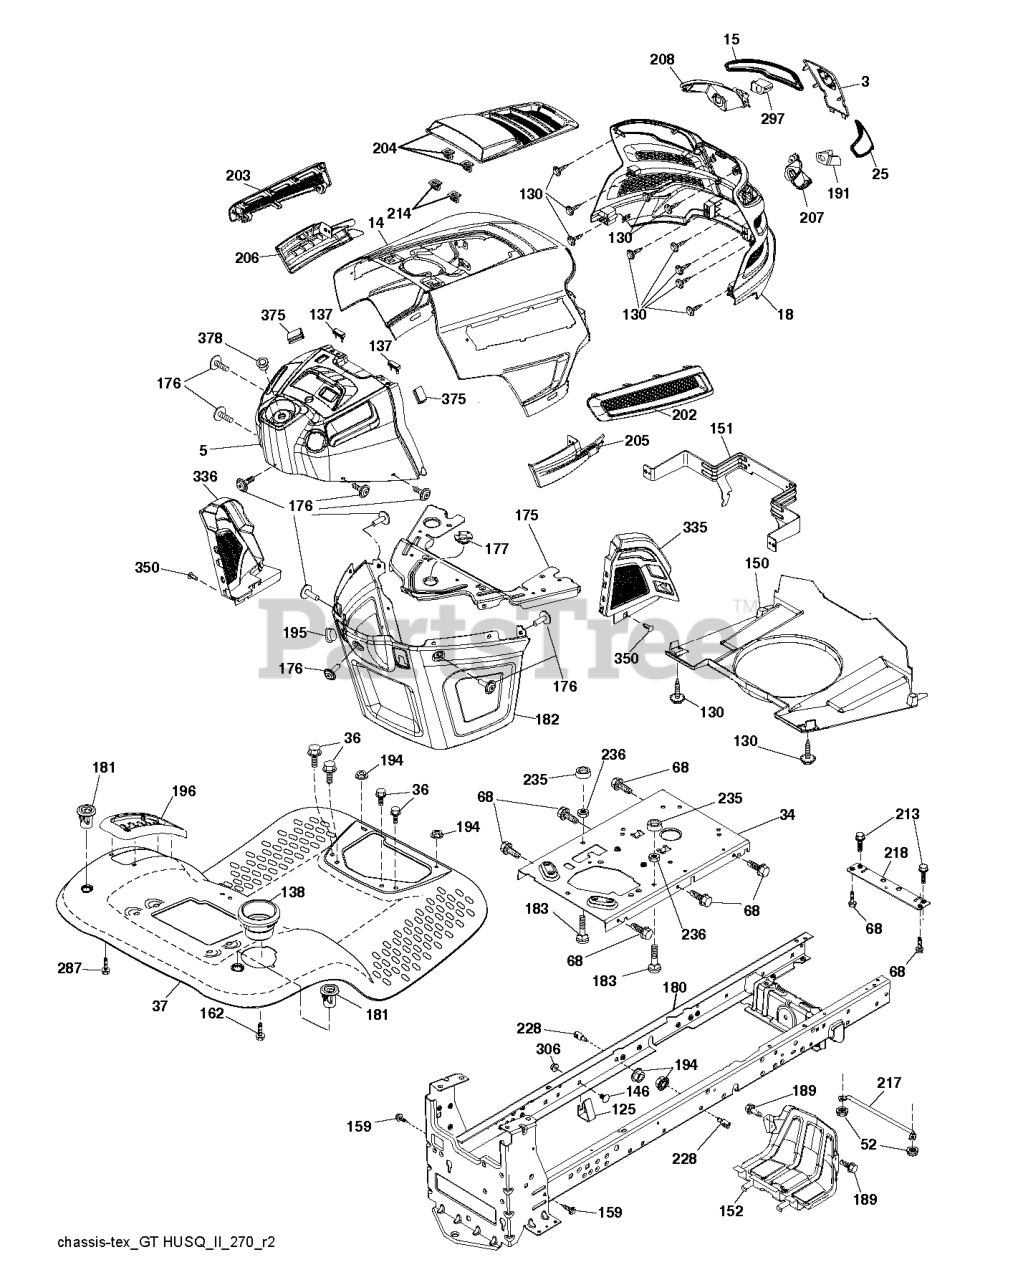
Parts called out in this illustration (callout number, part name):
3	APPLIQUE.SUBASM.GT.HUSQ.II
5	DASHBOARD.UPPER.ASM.GT2.X498
14	HOOD.ASM.HUSQVARNA.GT.TEX.ORAN
15	LENS.HEADLIGHT.LH.GTII.2011
25	LENS.HEADLIGHT.RH.GTII.2011
34	PLATE.ENGINE.WELDED.CHASSIS
36	SCREW 5/16"
37	FENDER.TLT.PDL.CNTRL.W/CPH.ORG
125	CLIP.FUEL.LINE
137	BUMPER DASH
138	HOLDER.CUP.LT.GREY
146	BOLT.RDHD.SHT.SQNK.3/8-16X5/8
150	AIR.DUCT.GTV2(2.54"RING HEIGHT
151	BRACKET.PIVOT.HOOD.GT.HUSQ.II
152	SHIELD.BROWNING.PNT.GT.V2
159	SCREW, 3/8-16X3/4
175	PLATE.PNT.CROSSMEMBER.HUSQ/PRE
176	SCREW.#10-24X5/8.RN.QU
177	BUSHING STEERING
180	CHASSIS
181	BUSHING.MNT.FEND.CRGO.TEX.49
182	DASH LOWER.HUSQ.PRED NO CRUISE
189	SCREW
191	INSERT.REFLECTIVE.RH.HUSQ.GTII
195	PLUG.HOLE.DASH.LOWER.12V.BLK
196	DECKLFT.CONSOL FULL ASSM GREY
202	VENT.SIDE.RH.GT.HUSQ.II.
203	VENT.SIDE.LH.GT.HUSQ.II.498
204	VENT.TOP.ASM.HUSQ.GT2
205	SIDE.TRIM.RH.GT.HUSQ.II
206	SIDE.TRIM.LH.GT.HUSQ.II.GRAY
207	HEADLIGHT.CUP.BEZEL.HUS.GT2.RH
208	HEADLIGHT.CUP.BEZEL.HUS.GT2.LH
213	SCREW HEXAGON HEAD SCREW 5/16-
214	CLIP.RETAINER.TINNER.
217	ROD.PIVOT.HOOD
218	X-PIECE.HOOD.STOP.NON/
228	STUD.W/"D"ANTI-ROTATION
236	NUT.CENTERLOCK.5/16-
287	SCREW 1/4X20
297	INSERT.REFLECTIVE.LH.HUSQ.GTII
306	NUT LOCK FLG 3/8-16 UNC
335	COVER.LOWER.DASH.RH.BLACK
336	COVER-LH.LOWER.DASH.GT2.BLACK
350	CLIP.X-MAS.TREE
375	BUMPER CLIP-ON. DASH 1"
378	BUSHING FLANGE; PLASTIC
